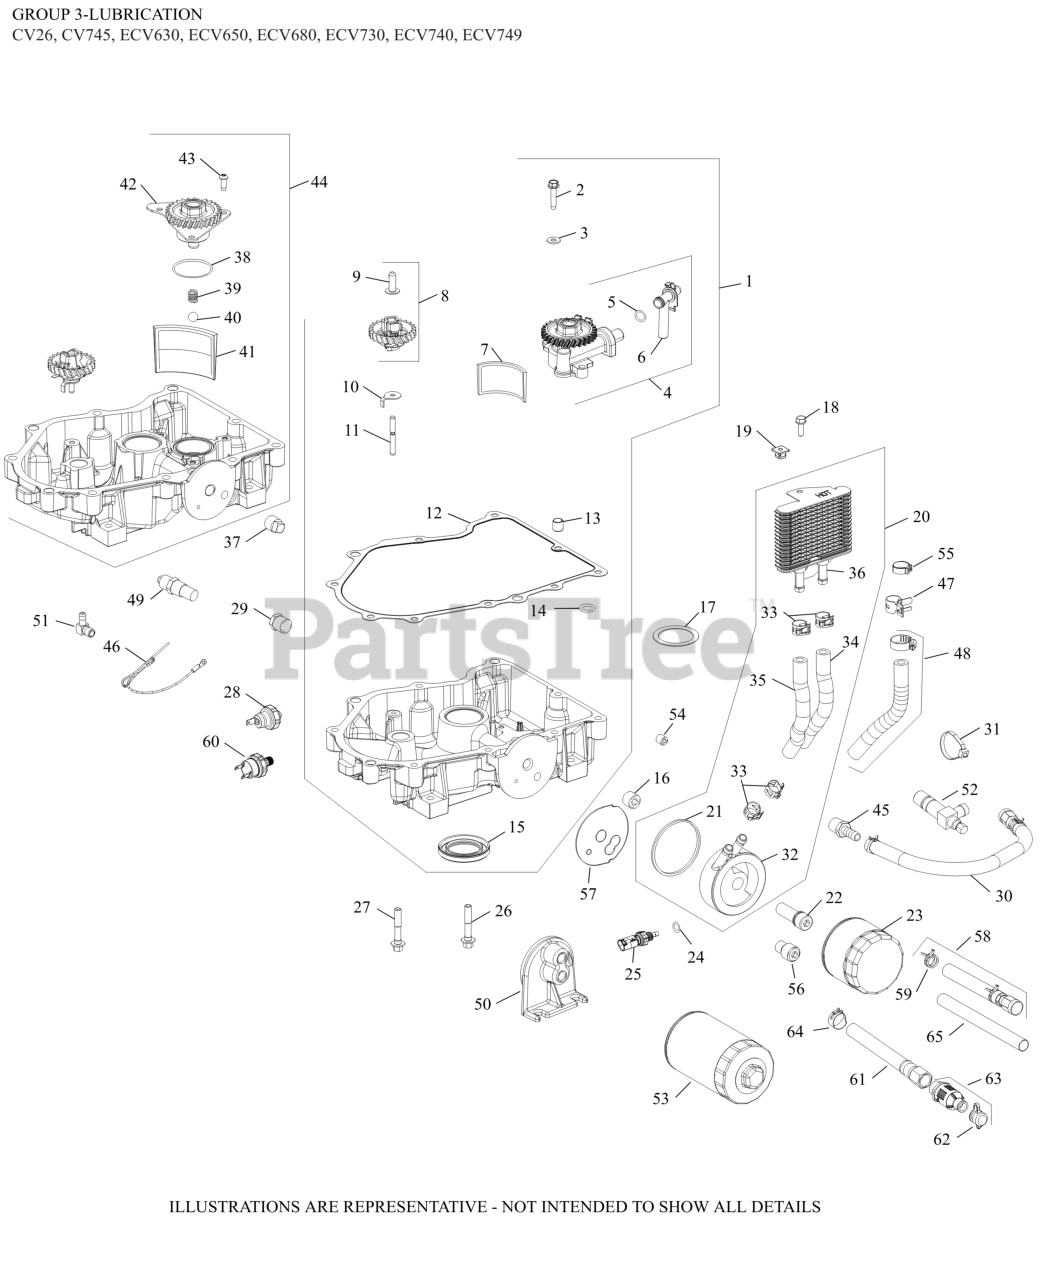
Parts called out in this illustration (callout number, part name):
1	KIT, OIL PAN ASSEMBLY - (#2419932S)
2	SCREW-USE 25 086 401-S
3	WASHER, FLAT 1/4" (O.D. 5/8")
4	PUMP ASSEMBLY, OIL-USE 24 393 53-S
5	O-RING, OIL PICK-UP
6	KIT, OIL PICK-UP TUBE-(#DSC)
7	SCREEN, OIL
8	KIT, GOVERNOR GEAR W/PIN
9	PIN, GOVERNOR REGULATING
10	TAB, LOCKING
11	SHAFT, GOVERNOR GEAR
12	KIT,OIL PAN GASKET-USE 24 041 66-S
16	PLUG, PIPE CTSK 3/8"
17	SHIM, THRUST (BLACK .686MM)
18	SCREW, TAP M6X1.7X18
19	NUT, PLASTIC - BLACK
20	KIT,OIL COOLR & DIVERTR ASSY (EFI)
21	O-RING, OIL COOLER
22	NIPPLE, OIL FILTER - (#2413608S)
23	OIL FILTER
24	O-RING (.5" DIA)
25	SENSOR, TEMPERATURE (EFI)
26	SCREW, HEX FLANGE
27	SCREW, FLG M8X1.25X45
28	SENSOR, OIL PSI
37	PLUG, SQ HD PIPE 3/8"
54	PLUG, CTSK PIPE 1/8"
